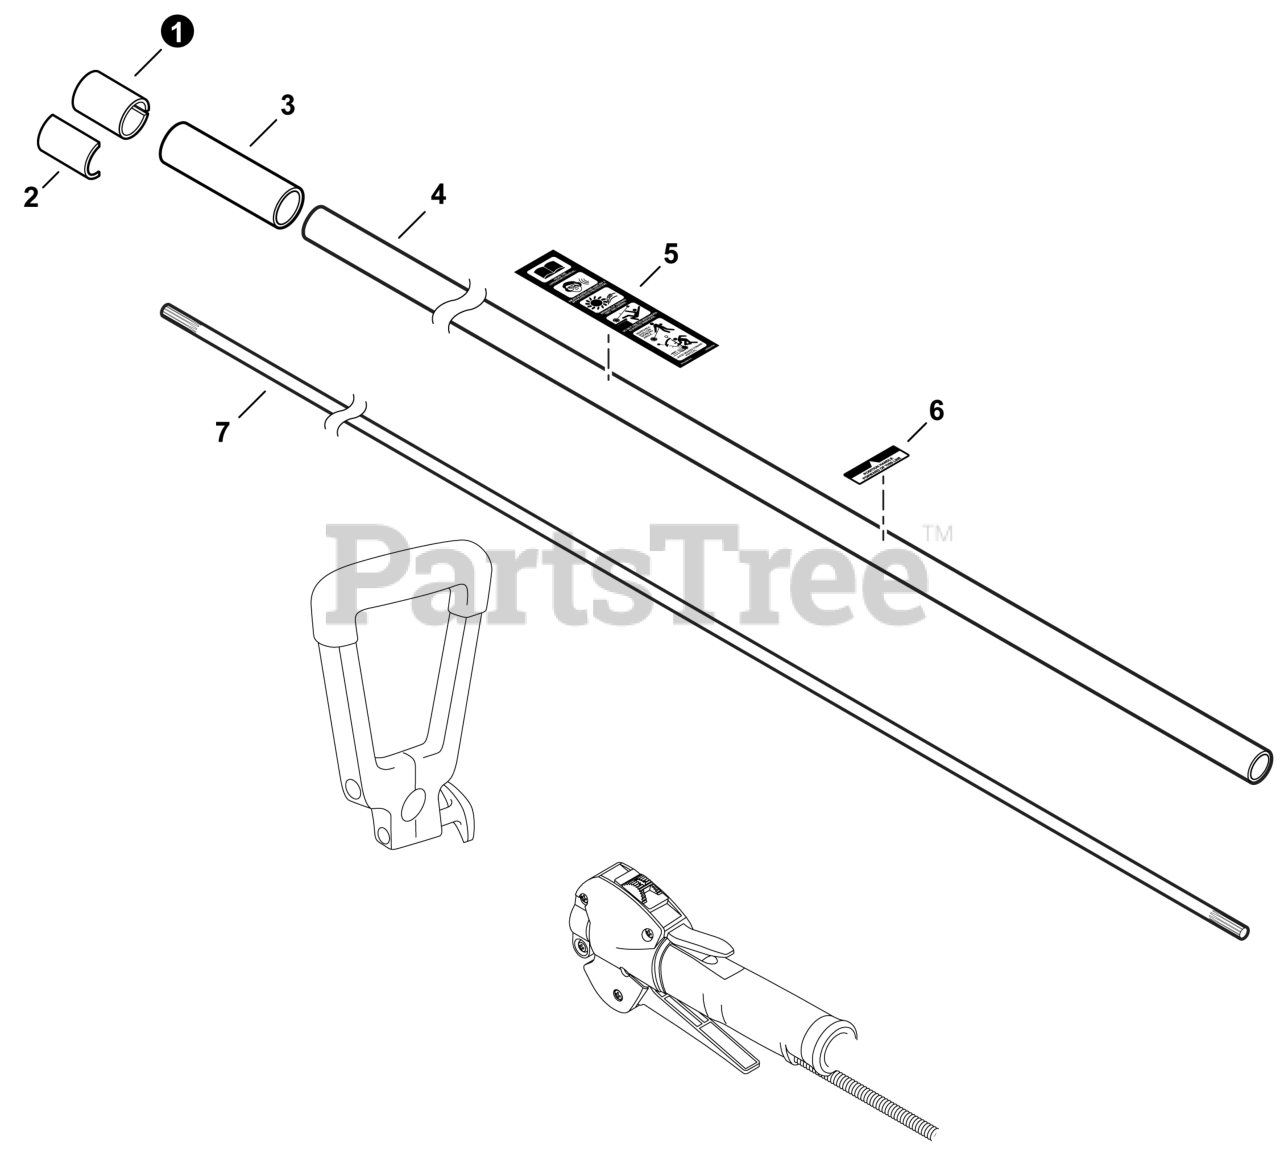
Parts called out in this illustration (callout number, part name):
1	COLLAR, MAIN PIPE - 25MM
3	PROTECTOR, MAIN PIPE 25 MM
4	MAIN PIPE ASSY
5	LABEL - CAUTION
6	LABEL - HANDLE
7	MAINSHAFT
